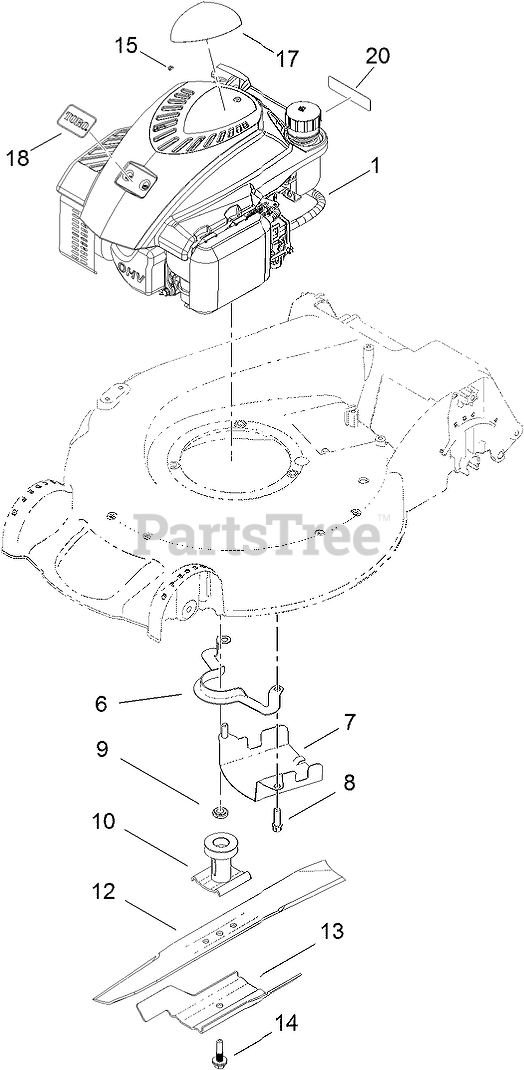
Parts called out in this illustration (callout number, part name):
1	ENGINE-1P65FC
6	GUIDE-BELT
7	SHIELD-GRASS
8	SCREW-TAPTITE
9	Spacer-Driver
10	DRIVER-BLADE
12	BLADE-RECYCLING
13	Accelerator-Blade
14	BOLT-BLADE
15	STOP-ROPE
17	DECAL-SHROUD
20	DECAL-ARRESTER, SPARK
